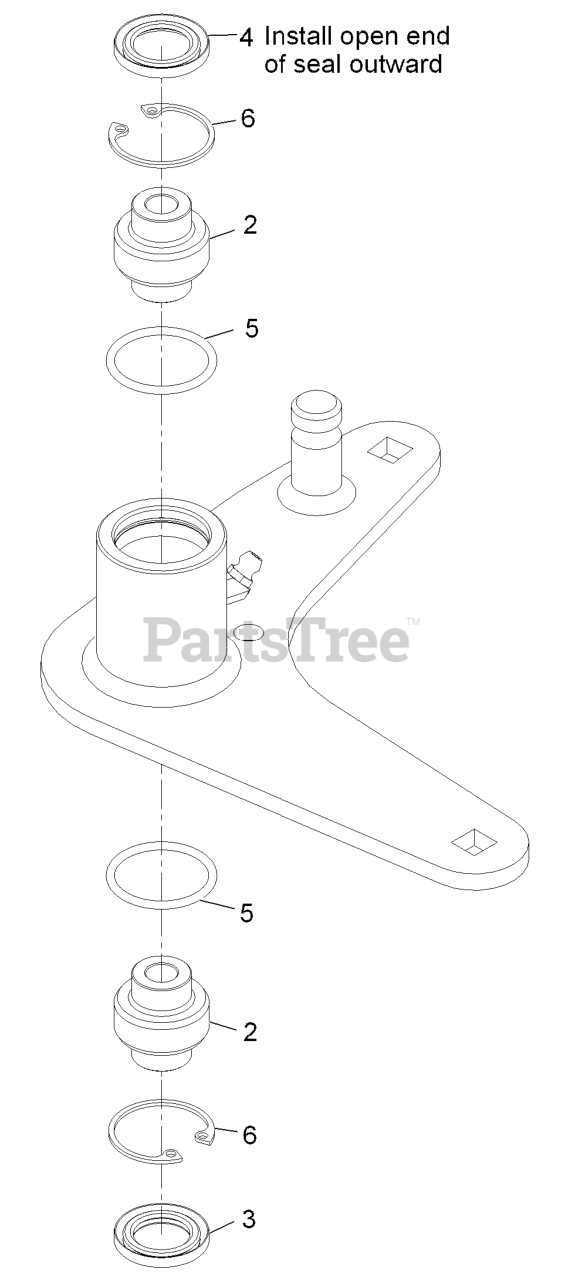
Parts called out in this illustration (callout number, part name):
2	Bearing-Spherical
3	Seal-Lip, Double
4	Seal-Single Lip
6	Ring-Retaining
